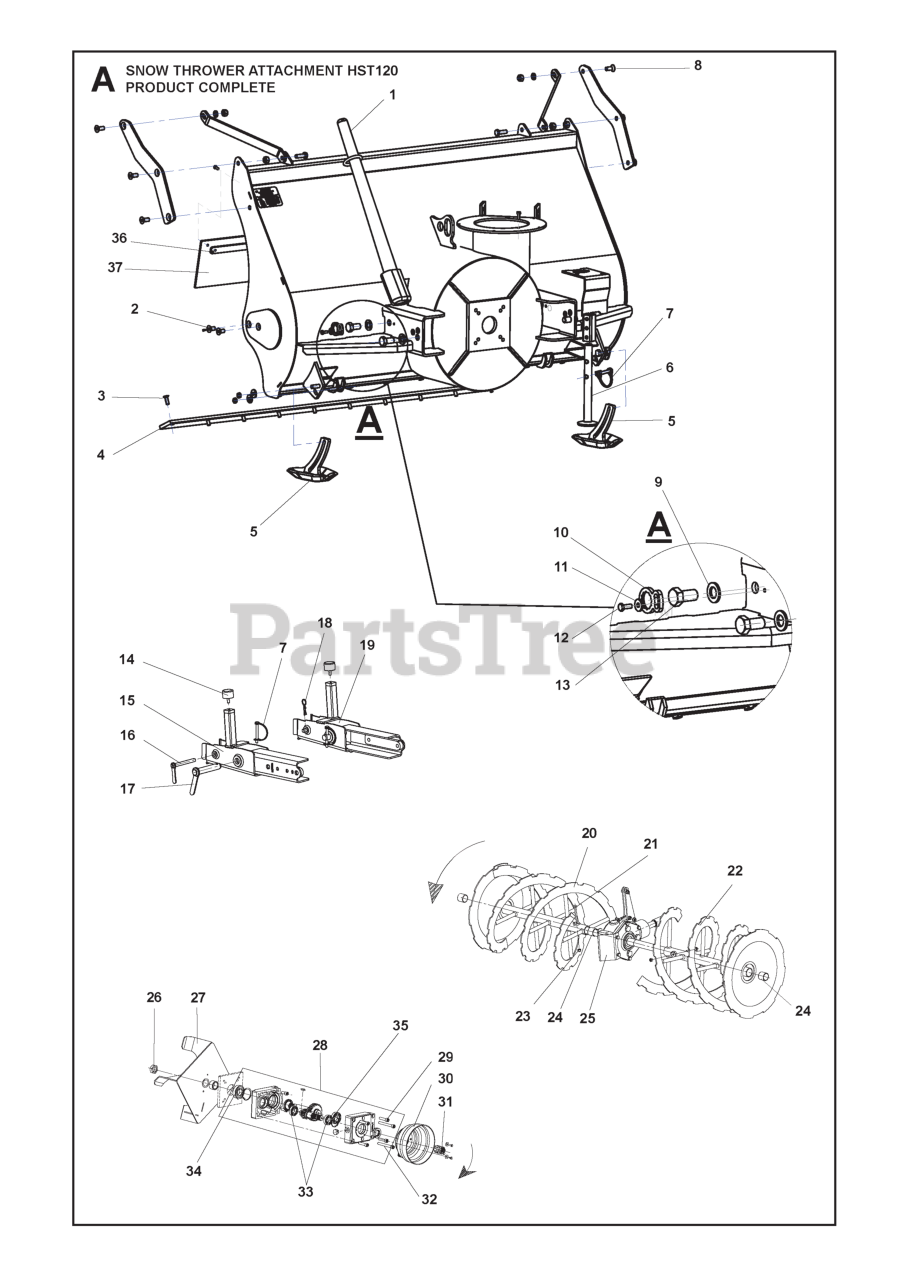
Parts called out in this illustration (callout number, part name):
11	WASHER - 26X6.5X1.6
12	BOLT FLANGE - M6X20
23	NUT LOCK - M8, NYLOCK
33	Ball Bearing 6005-2rs
